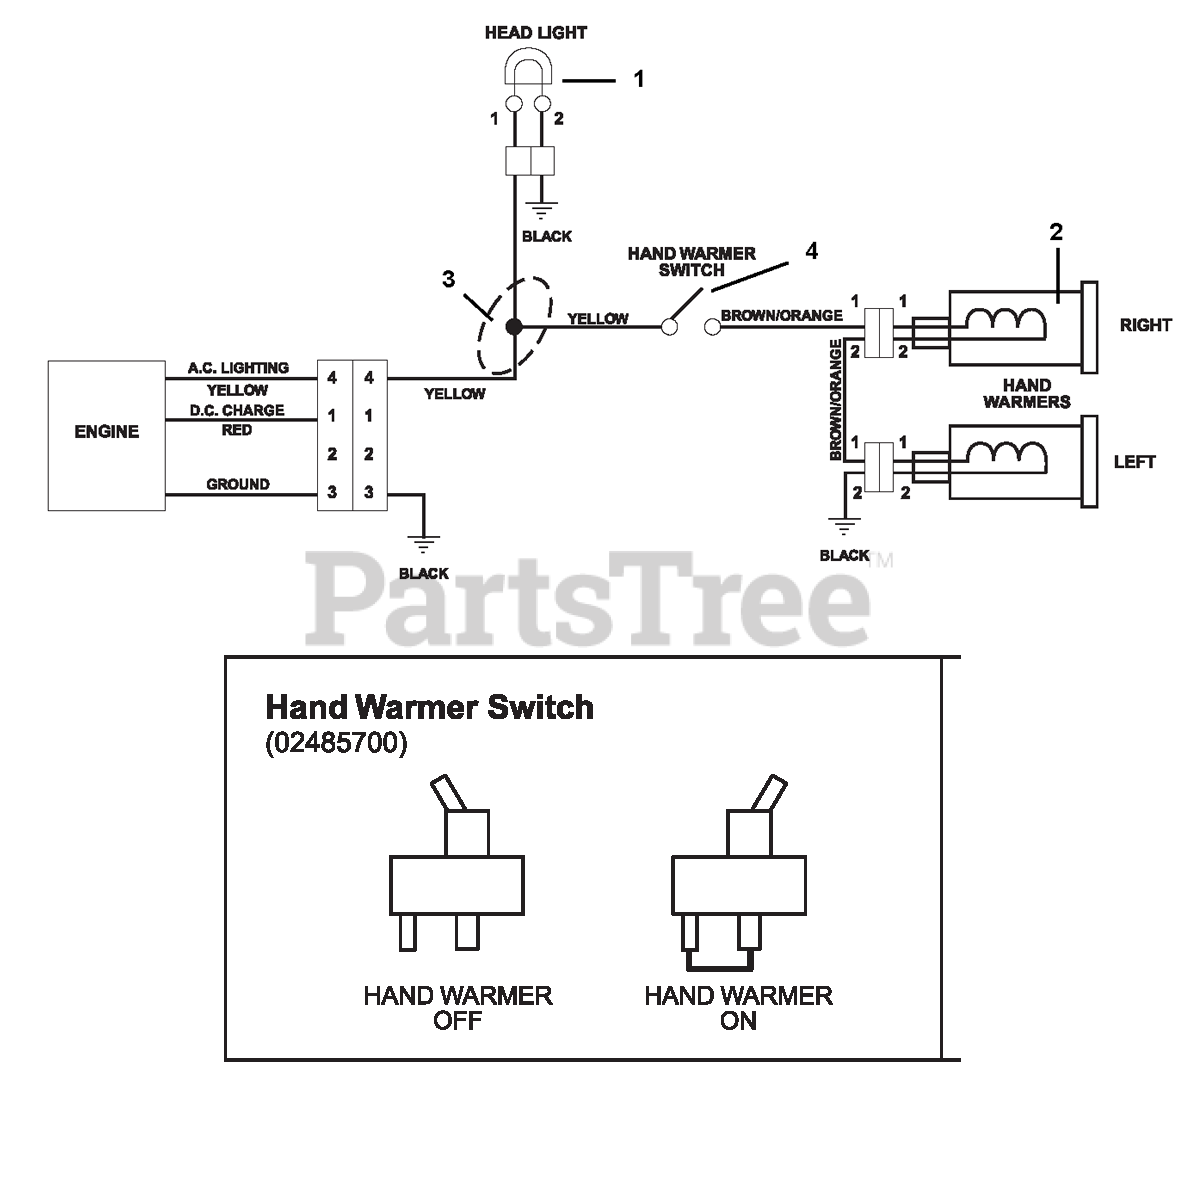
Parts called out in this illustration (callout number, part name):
1	LIGHT, HALOGEN ASSY.
2	HEATED GRIP, MAGURA
3	HARNESS, WIRE-LIGHT&HANDWARMER
4	SWITCH, ON/OFF
